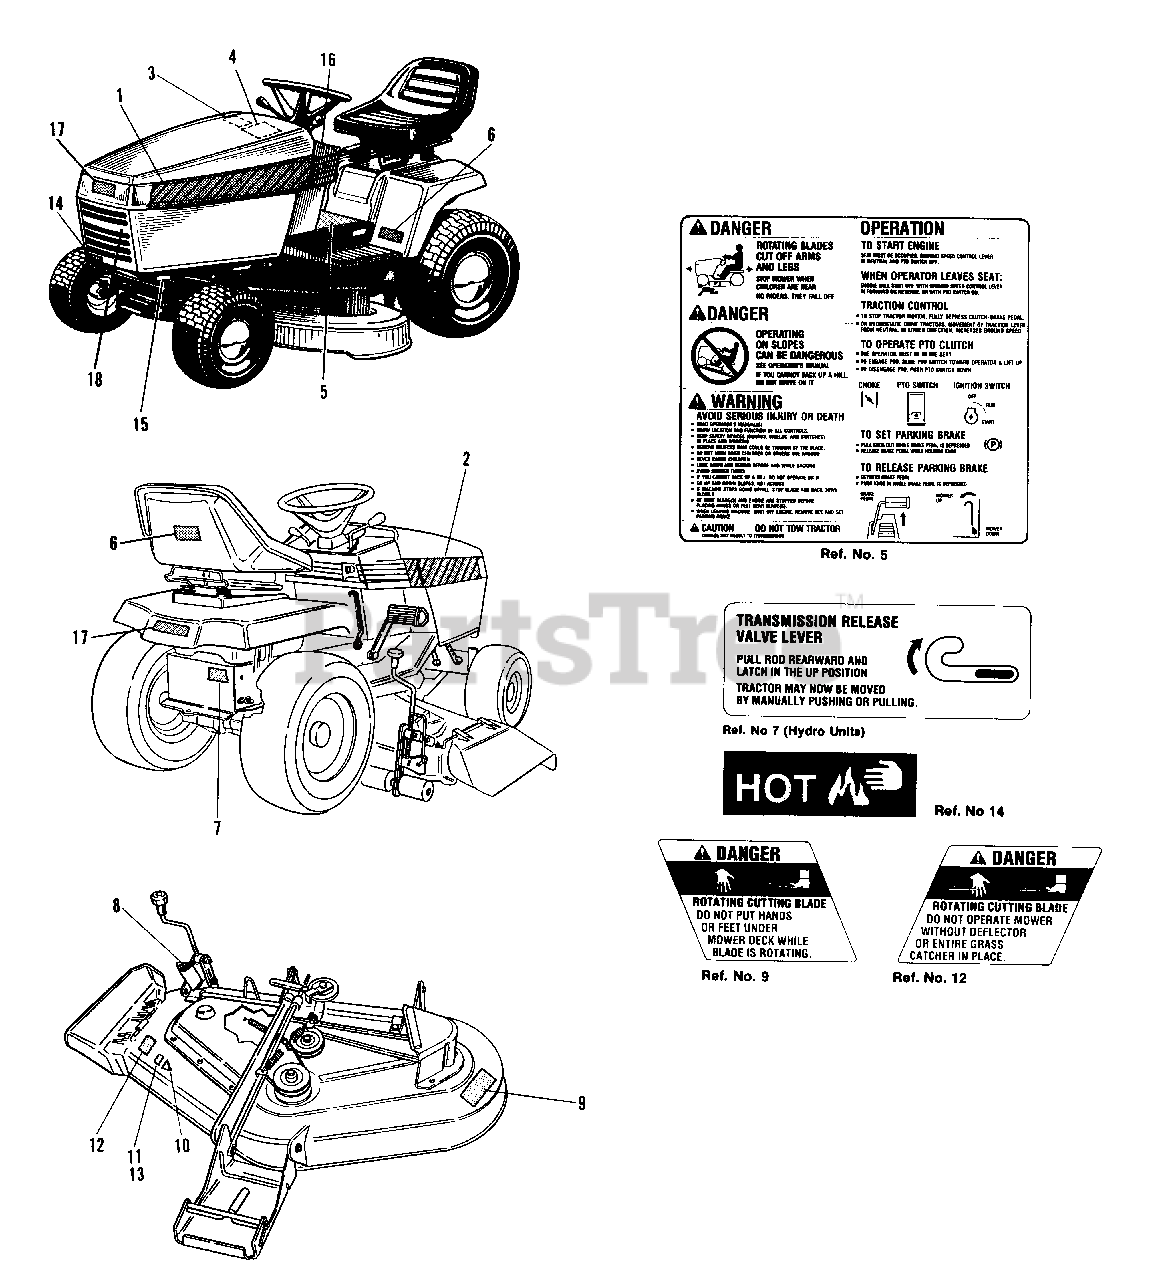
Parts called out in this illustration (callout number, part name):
1	DECAL, Hood, L.H., Deutz Allis-All Models
1	DECAL, Hood, L.H., AGCO Allis, 16H
1	DECAL, Hood, L.H., AGCO Allis, 14H
1	DECAL, Hood, L.H., AGCO Allis, 12.5H
2	DECAL, Hood, R.H. Deutz Allis-All Models
2	DECAL, Hood, R.H. AGCO Allis, 16H
2	DECAL, Hood, R.H. AGCO Allis, 14H
2	DECAL, Hood, R.H. AGCO Allis, 12.5H
2	DECAL, Hood, R.H., AGCO Allis, 12.5G
3	DECAL, Paint (Older Models Only)
4	DECAL, Belt, Blade (Deutz Allis Models)
4	DECAL, Belt, Blade (AGCO Allis Models)
5	DECAL, Operating Inst.
6	DECAL, USA Logo
7	DECAL, Push Valve (Hydrostatic Units only)
8	DECAL, Mower Height
9	DECAL, Danger (Hand Under Deck)
10	DECAL, OPEI
11	DECAL, Cutting Width, 38"
12	DECAL, Danger (Chute in Place)
13	DECAL, Cutting Width, 44"
14	DECAL, Grille, Hot
15	I.D. PLATE
16	DECAL, Choke (Dash), 12.5 and 14 HP Kohler Only
17	DECAL, Seat Deck, 1613H (Deutz Allis)
17	DECAL, Seat Deck, 1616H (Deutz Allis)
17	DECAL, Seat Deck, 1613G (Deutz Allis)
17	DECAL, AGCO Allis Badge
18	DECAL, 1613H (DeutzAllis)
18	DECAL, 1616H (Deutz Allis)
18	DECAL, 1613G (Deutz Allis)
18	DECAL, Battery
